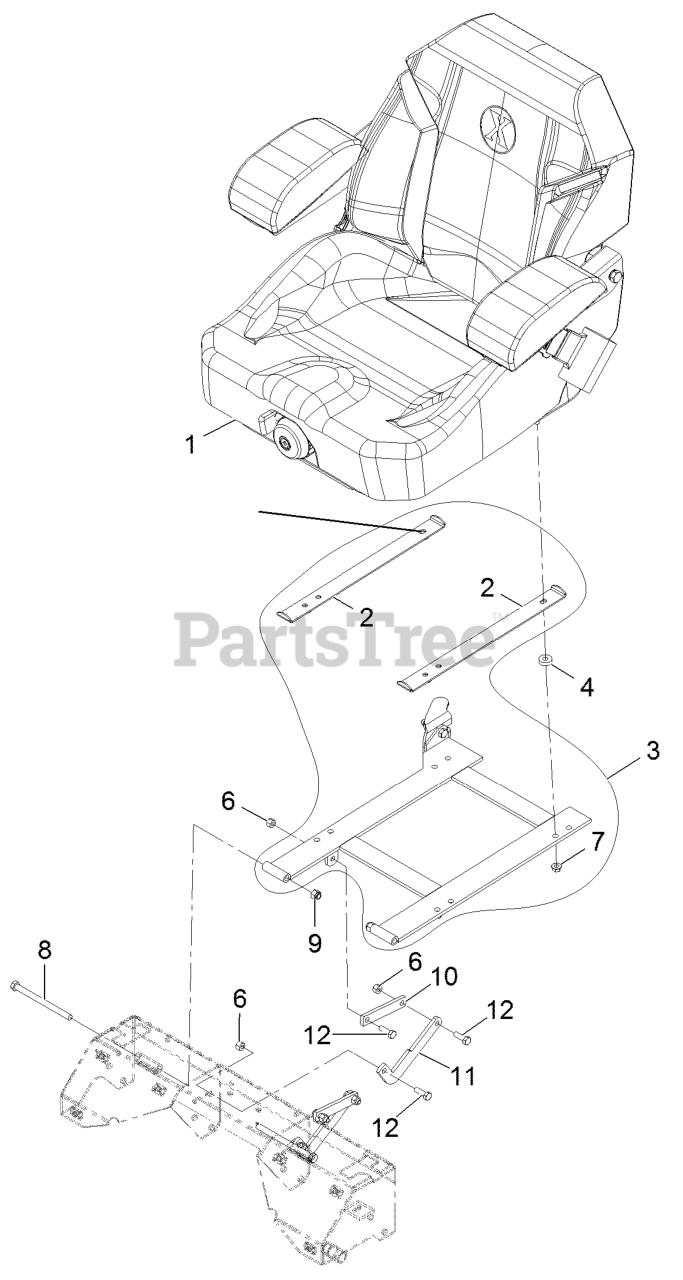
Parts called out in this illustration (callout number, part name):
1	KIT-SUSPENSION SEAT
2	STOP/SPACER-SEAT
3	KIT,SEAT FRAME SERVICE
6	NUT-LOCK, NI
8	SCREW-HH
9	NUT-LOCK, NI
10	LINK-STOP, SEAT
11	LINK-STOP, SEAT
12	SCREW-HH
